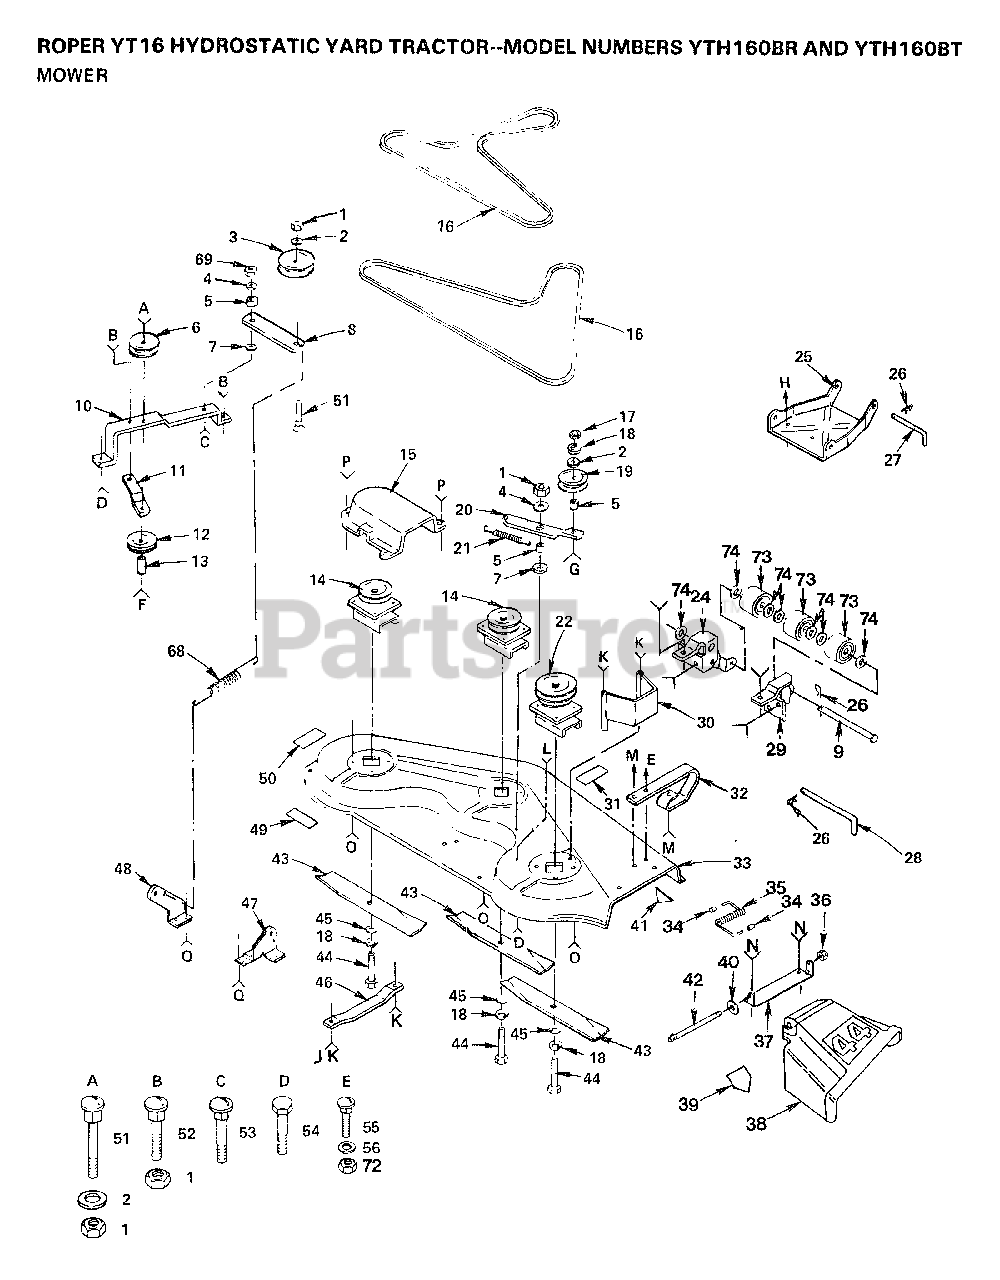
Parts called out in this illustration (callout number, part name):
2	WASHER
3	IDLER-FLAT T
5	SPACER RETAINER
6	IDLER-INSIDE T
7	"WASHER, WEAR LT"
8	ARM IDLER HYT
9	PIVOT PIN T
10	"SUPPORT YT, BAR"
11	BRACE-IDLER YT
12	IDLER-FLAT YTV
15	GUARD YT
16	BELT-V.79.1.MWR
17	NUT.HEX.3/8-16UNC
18	LOCKWASHER
19	IDLER.FLAT.GTV
20	ARM-IDLER YT
24	BRACKET LH YTH
25	LINK.PARALLEL
27	"ROD, FRT. PARAL T"
28	HINGE PIN T
29	BRACKET RH YTH
30	GUARD BELT HYT
31	DECAL.WARNING.T
38	DEFLECTOR SHIELD
39	DECAL HYT
40	WASHER
41	DECAL - SAFETY STANDARD
42	ROD-HINGE T
44	BOLT.3/8-24X1-1/2
45	WASHER
46	RUNNER-LH M
49	DECAL HYT
50	DECAL-INST YT
51	BOLT
53	BOLT
55	BOLT
56	WASHER
68	"SPRING.EXT.8.5"""
69	LOCKNUT
71	BOLT
73	ROLLER T
74	WASHER T
